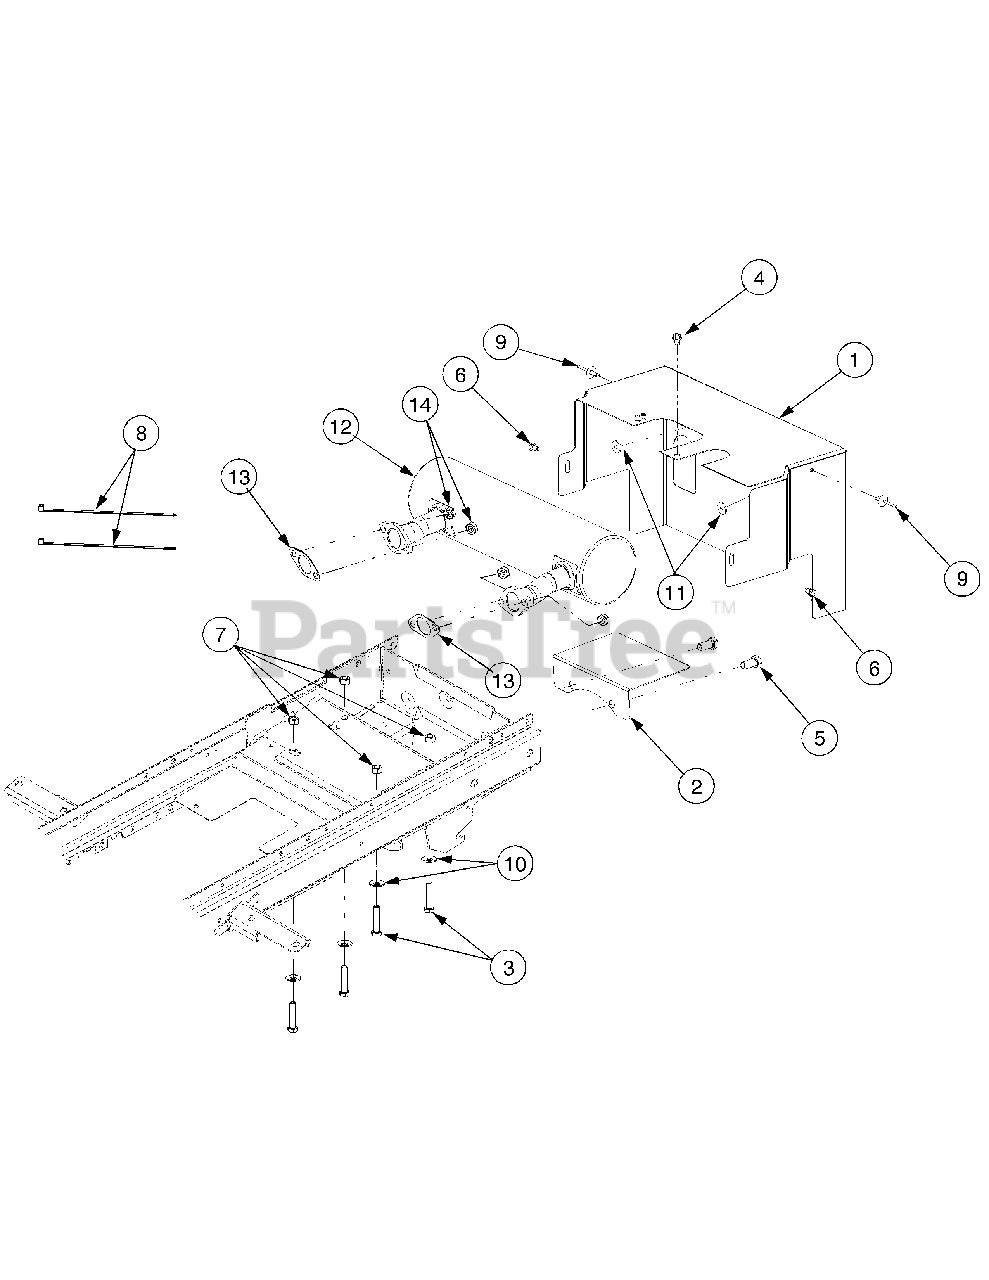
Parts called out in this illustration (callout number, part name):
1	Shield, Heat
2	Shield, Clutch
3	Bolt, Eng Mount, 3/8-24 x 1.75 GR5
4	Screw, Hx Wsh Hd Tapp, 1/4-20 x .375
5	Screw, Hx Cap Lock, 3/8-16 x .75 Gr5
6	Screw, Hex Cap, M6 x 1 x 10
7	Nut, Hex Lock, 3/8-24
8	Tie, Cable
9	Rivet, Pop, 3/16 x .45
10	Washer, Bell, .380 x .88 x .062
11	Washer, Flat, .194 x .62 x .063
12	Muffler Assembly
13	Gasket, Exhaust
14	Nut, Hex Flange
